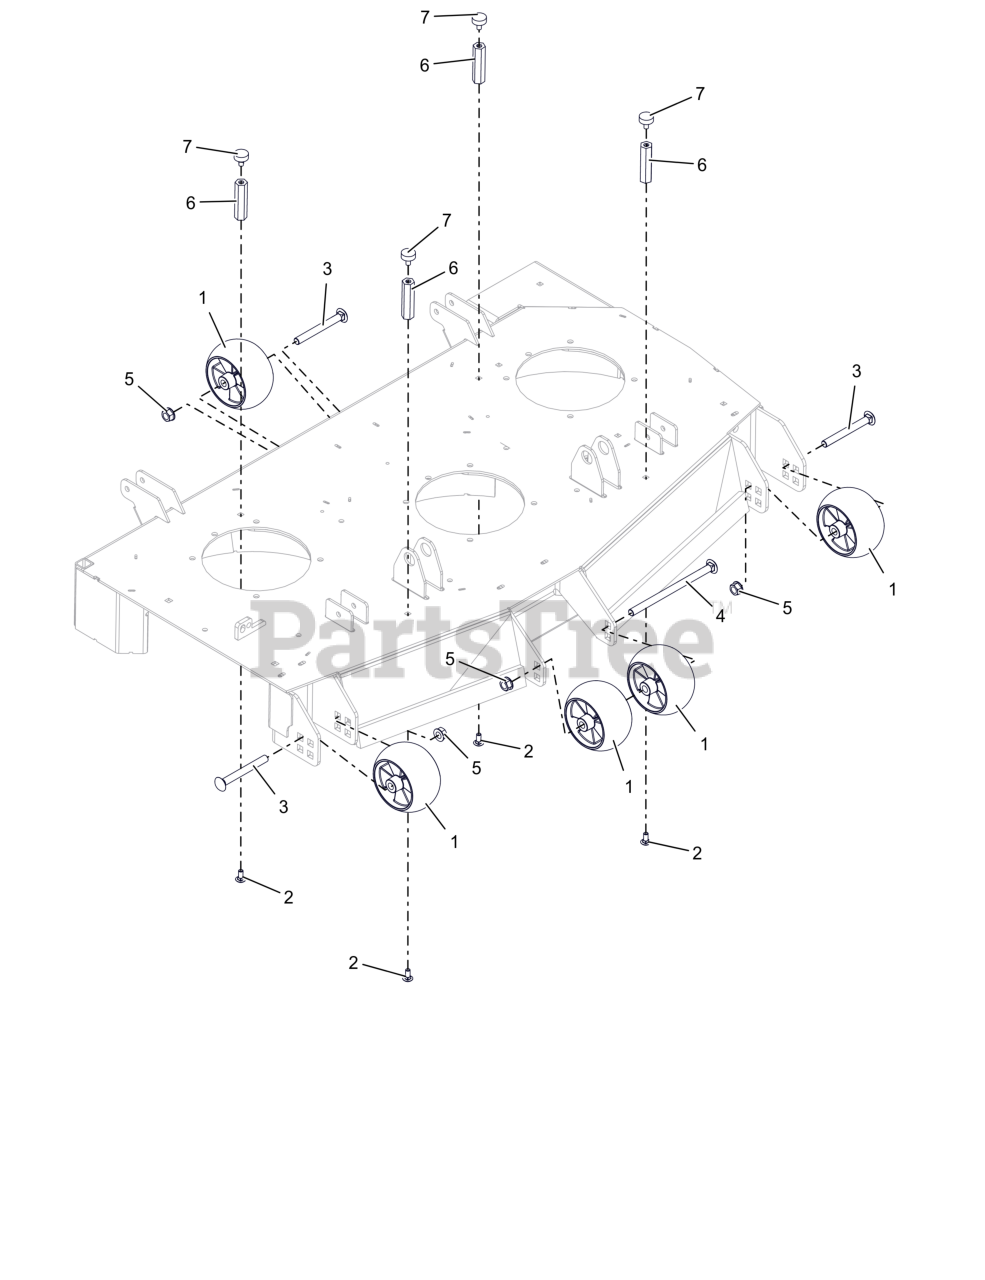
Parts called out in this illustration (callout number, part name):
1	WHEEL, ANTI SCALP - 5X3 CTR W/RIBS
2	BTL,RHSN .313-18 X 0.75 G5 ZCC LT
3	BLT,RHNS .50-13X4.50 G5 ZCC NS
4	BLT,RHSN .50-13X8.00 G5 ZCC NS
5	NUT-LK-CTR-FLG .500-13 GG ZCC
6	NUT, COUPLING .31-18 X 3.00
7	BUMPER, RUBBER
